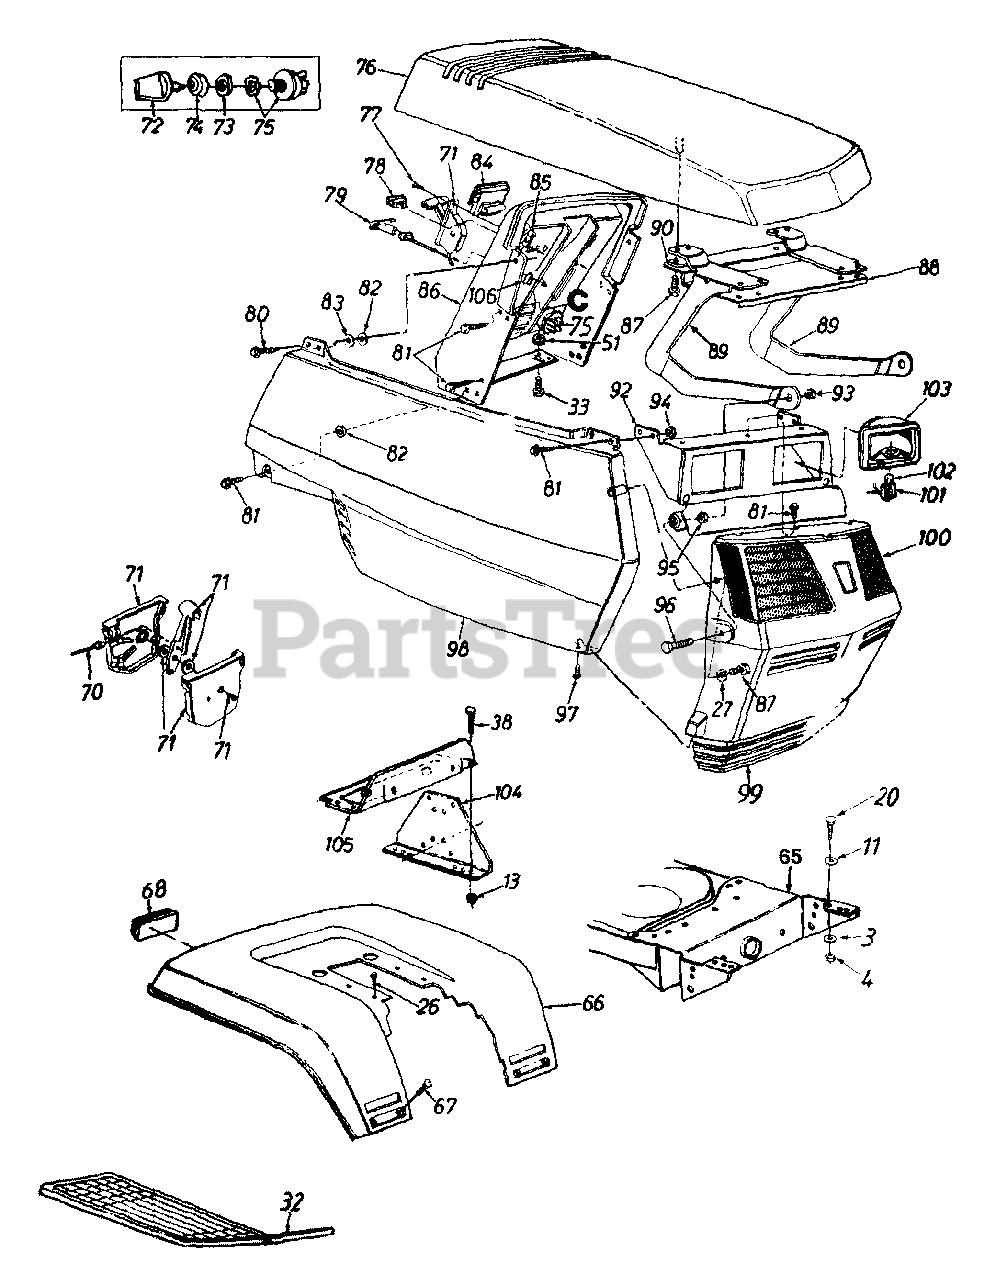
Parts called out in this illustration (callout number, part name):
11	L-Wash. 5/16" I.D.
13	Hex Sems Nut 1/4-20 Thd.
26	Hex Wash. Hd. AB-Tap Scr. 5/16 x .75" Lg.
27	Fl-Wash. .218" I.D. x .5" O.D.
32	Rubber Foot Pad-L.H.
33	Hex Bolt 5/16-18 x .75" Lg.
38	Hex Bolt 1/4-20 x .62" Lg.
51	Hex Sems Nut 5/16-18 Thd.
68	Reflector
70	Throttle Wire 18.5" Lg.
71	Throttle Control Box Ass'y.
72	Ignition Key
73	Ignition Switch Nut
74	Ignition Switch Cap
75	Ignition Switch
76	Hood
77	Truss Mach. AB-Tap Scr. #10 x .5" Lg.
78	Light Switch
79	Choke Control 29" Lg.
80	Hex Wash. Hd. Tap Scr. 1/4 x .75" Lg.
81	Hex Tap Scr. 1/4-20 x .5" Lg.
82	Push Nut Fastener
83	Fl-Wash. .27" I.D. x .948"
84	Ammeter
85	Speed Nut 1/4-20 Thd.
86	Dash Panel
87	Hex Wash. Hd. B-Tap Scr. 1/4 x .75" Lg.
94	Hex L-Nut 1/4-20 Thd.
95	Hex Jam Nut 5/16-18 Thd.
96	Hex Bolt 5/16-18 x 7/8" Lg.
97	Truss Mach. B-Tap Scr. #10 x .5" Lg.
98	Side Cover-R.H.
99	Grille
100	Lens-L.H.
101	Twist Lock-Lamp Socket
102	Lamp
103	Headlight Housing
